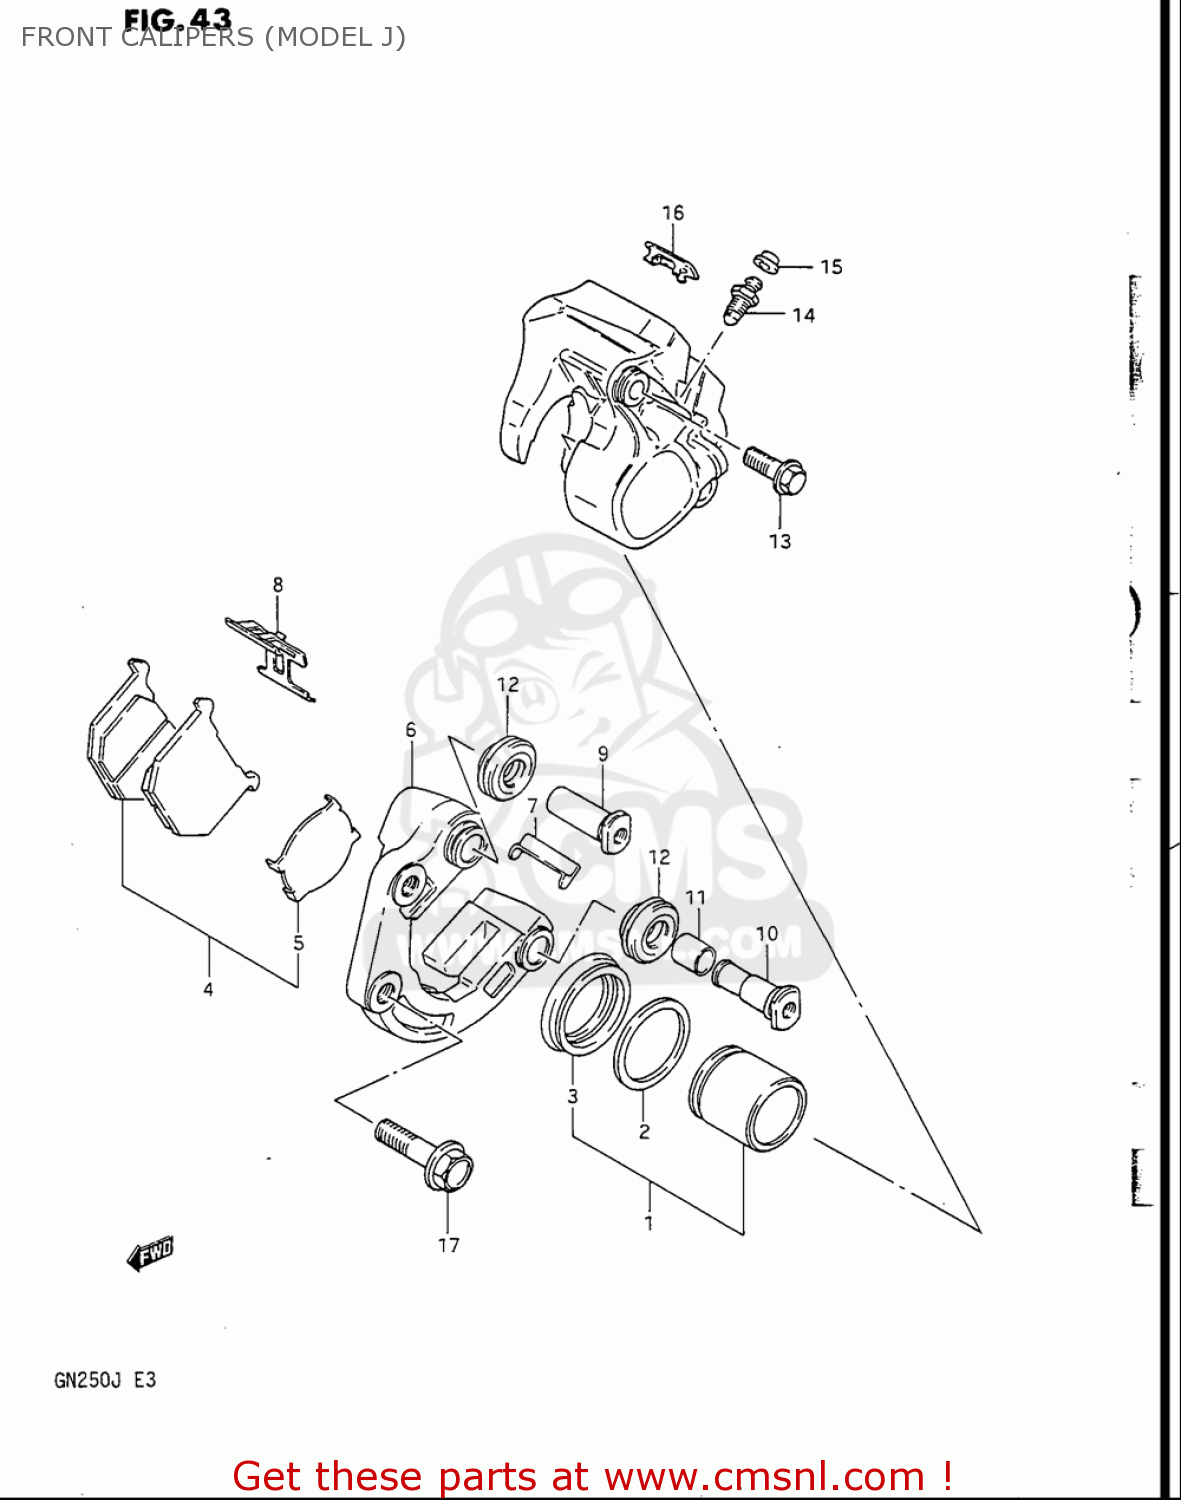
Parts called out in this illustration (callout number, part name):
1	PISTON SET
2	SEAL,PISTON
3	BOOT,PISTON
4	PAD SET (NAS)
5	SHIM,PAD
7	GUIDE,PAD
8	SPRING,PAD
9	AXLE NO.1
10	AXLE NO.2
11	BUSH,AXLE
12	BOOT,AXLE
13	BOLT
14	BLEEDER
15	CAP,BLEEDER PLUG
16	COVER
17	BOLT
